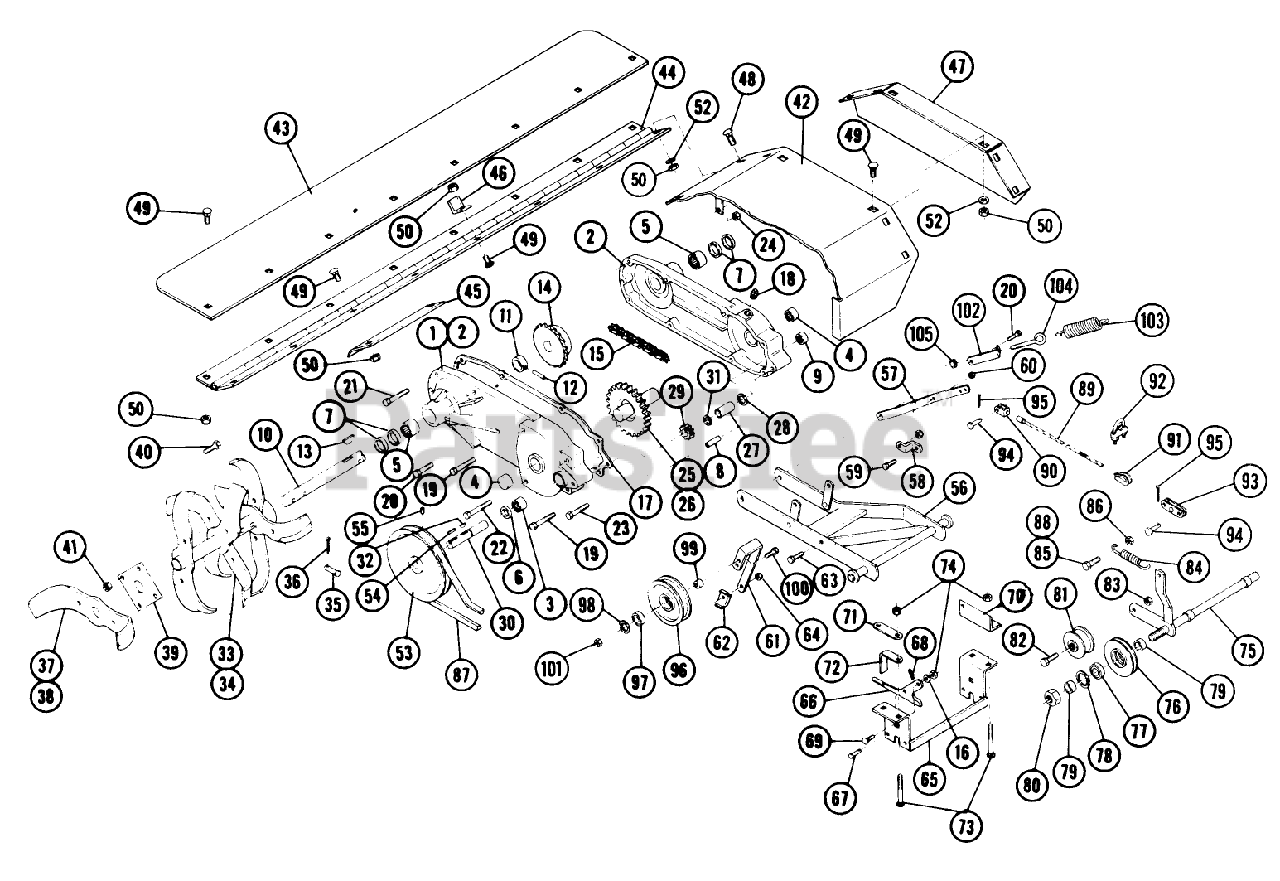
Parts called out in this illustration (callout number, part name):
3	BEARING-NEEDLE
4	BEARING-NEEDLE
5	BEARING-NEEDLE
6	SEAL-OIL
8	ROLL PIN 3/8 X 1
9	BEARING-NEEDLE
12	ROLL PIN 5/16 X 2
15	CHAIN
25	BULLT 258
28	WASHER-THRUST
30	SHAFT-INPUT
32	Key
35	PIN-CLEVIS
46	Stop Bracket
49	CARRIAGE BOLT -4
52	WASHER 5/16 SAE
66	PLATE-LATCHING
68	Hairpin
71	BRACKET-REAR LINK MOUNTING
72	SPACER-BRACKET
77	BEARING-BALL
78	Ring-Snap
79	SPACER
81	IDLER PULLEY
84	SPRING-BRAKE
87	V BELT
92	U BOLT
97	BEARING
98	INTERNAL SNAPRING
103	SPRING
104	EYEBOLT
